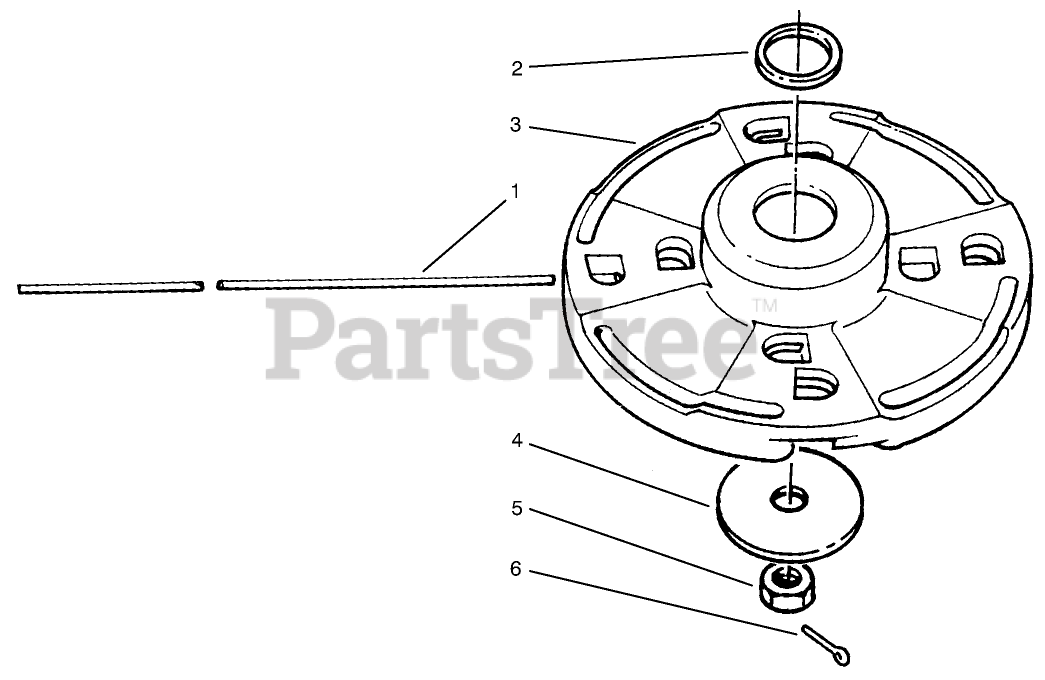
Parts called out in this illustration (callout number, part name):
1	Line-Cutting .105 Dia.
2	SPACER
3	Cutter Head Assembly (Incl. Ref.#2)
4	WASHER
6	1/16 X 1 LG COTTER PIN
